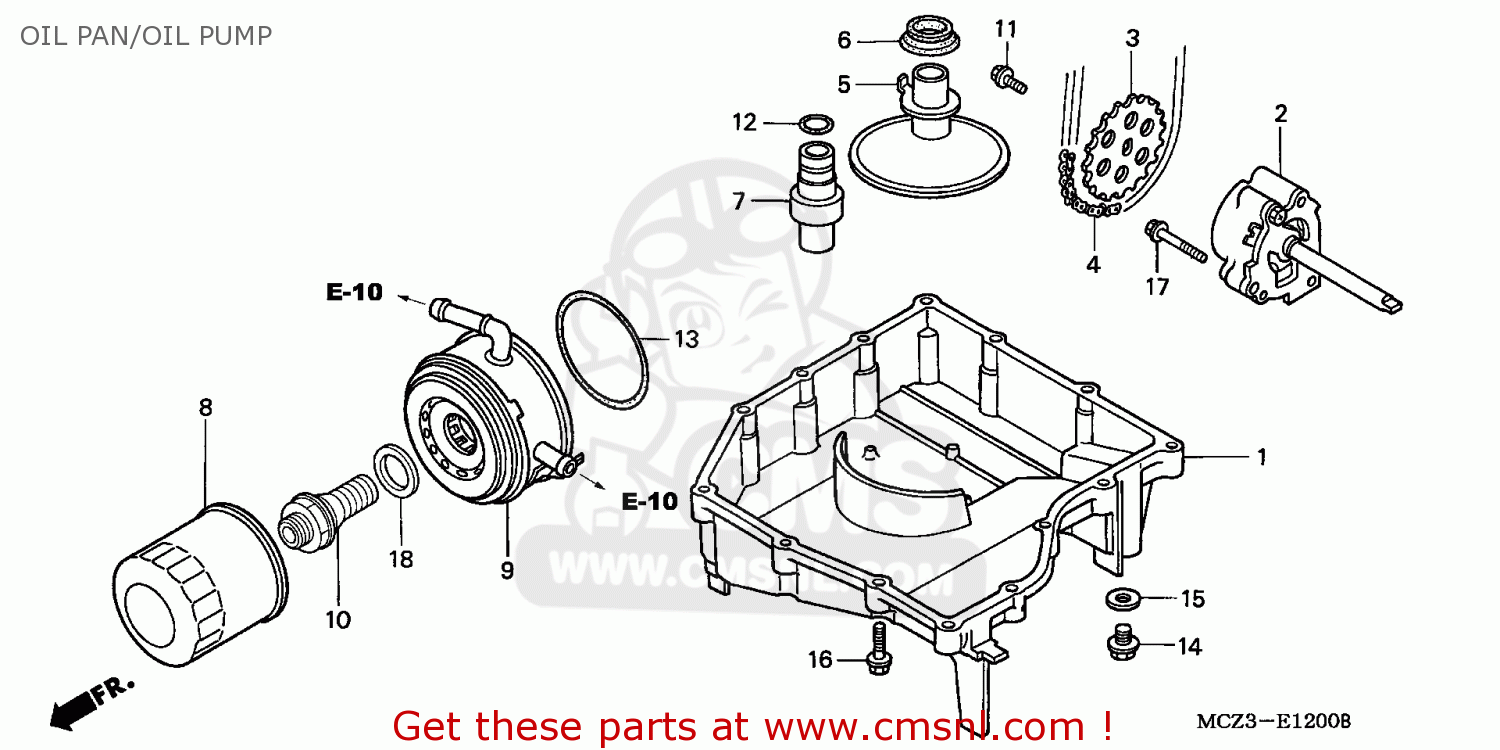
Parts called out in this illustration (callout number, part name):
1	OIL PAN
2	OIL PUMP ASSY
3	SPROCKET,OIL PUMP
4	CHAIN,OIL PUMP (2
5	STRAINER COMP,OIL
6	PACKING,OIL STRAI (NAS)
7	VALVE ASSY,RELIEF
8	OIL FILTER CARTRI
9	COOLER COMP,OIL
10	BOLT,OIL COOLER
11	BOLT-WASHER,6X12
12	O-RING,14.8X2.2
13	O-RING, 62.4X3.1
14	BOLT DRAIN 12MM
16	BOLT,FLANGE,NSHF,
17	BOLT,FLANGE,6X40
18	WASHER,SPG.24MM .
